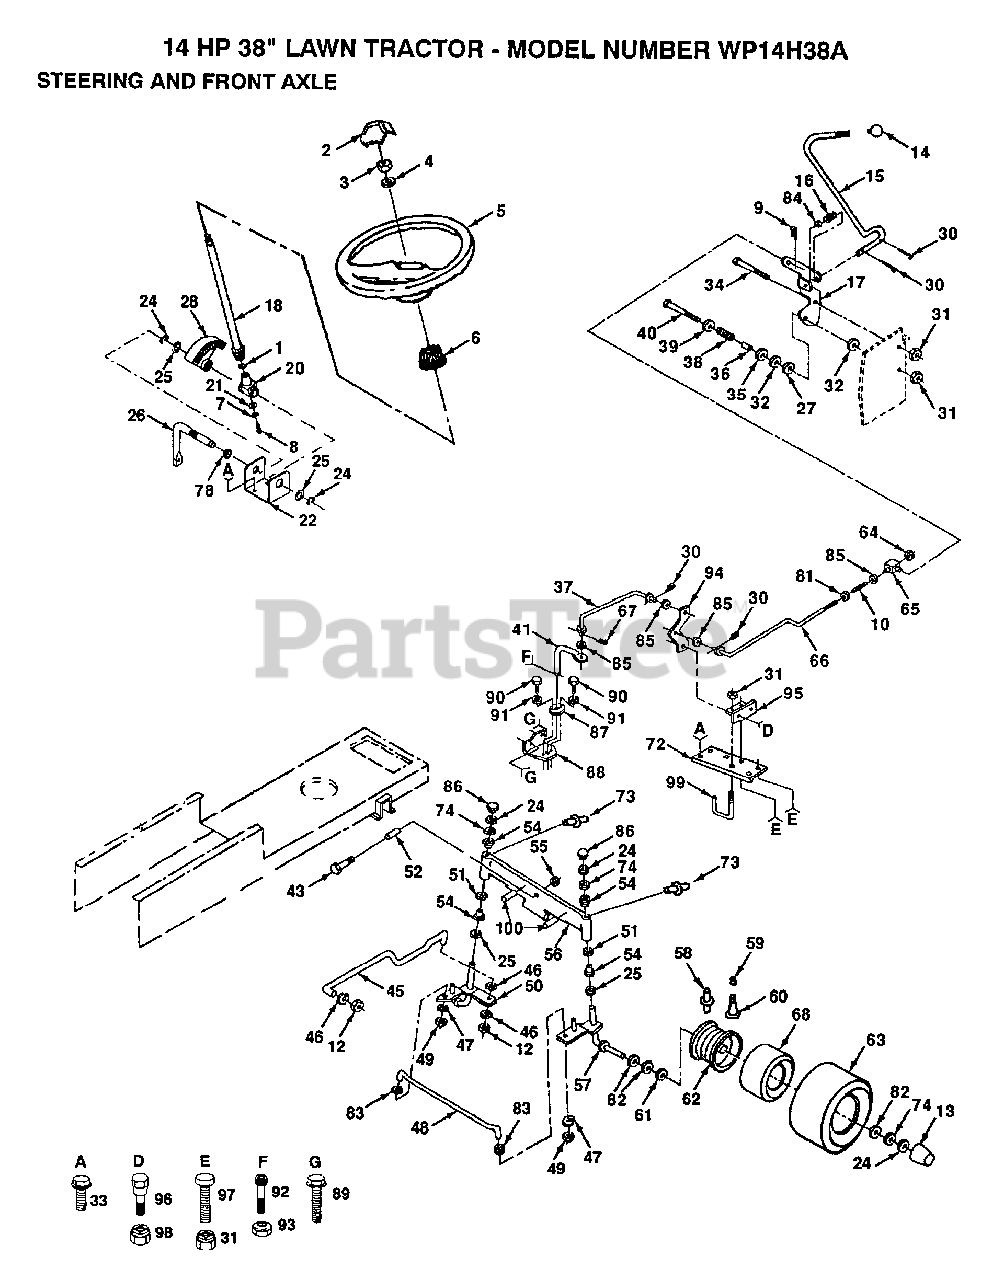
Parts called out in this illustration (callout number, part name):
1	THRUST WASHER
2	"INSERT,STR WHEEL"
4	WASHER
6	ADAPTER LT
7	LOCKWASHER
8	"SCREW,SPECIAL"
9	SPRING.RETAINER
10	SPRING GTV
13	HUB CAP
14	KNOB.DUCKHEAD.1/2
15	ROD.YTH
16	SPRING TORSION
17	BRKT CONTROL HYT
20	SUPPORT.SHAFT
22	"BRKT,STEERING"
24	RING
25	WASHER .T
27	WASHER HYT
30	COTTER PIN
32	WASHER FRIC HYT
33	SCREW
34	BOLT HYT
35	WASHER D
36	SPACER HYT
37	LINK CONTROL
38	SPRING HYT
39	WASHER
40	BOLT - HEX 3/8 - 16 X 3
41	ARM ASM PUMP
43	BOLT HEX 5/8-11
46	LOCKWASHER
47	LOCKWASHER
48	TIE ROD
49	NUT.LOCK.5/16-24
50	SPINDLE LH
51	WASHER
52	BEARING
54	COL. SRTG. BEAR.
57	SPINDLE RH
58	FITTING LT
59	VALVE STEM LT
60	VALVE CAP
61	"FLANGE, BEARING"
64	NUT
65	TRUNION HYT
66	ROD ADJ CONTROL
67	RETAINER M
68	TUBE.5.3/4.5/6
72	BRACKET
73	ZERK M
74	WASHER
78	NYLINER T
81	WASHER T
82	WASHER
83	WASHER M
84	WASHER
85	WASHER T
86	CAP
87	GUIDE CONTROL
88	BRKT
89	SCREW
91	WASHER
92	SCREW
93	LOCKNUT
94	BELLCRANK
95	BRKT BELLCRANK
96	SHOULDER BOLT LT
97	BOLT
99	KEEPER
100	AXLE PIN
